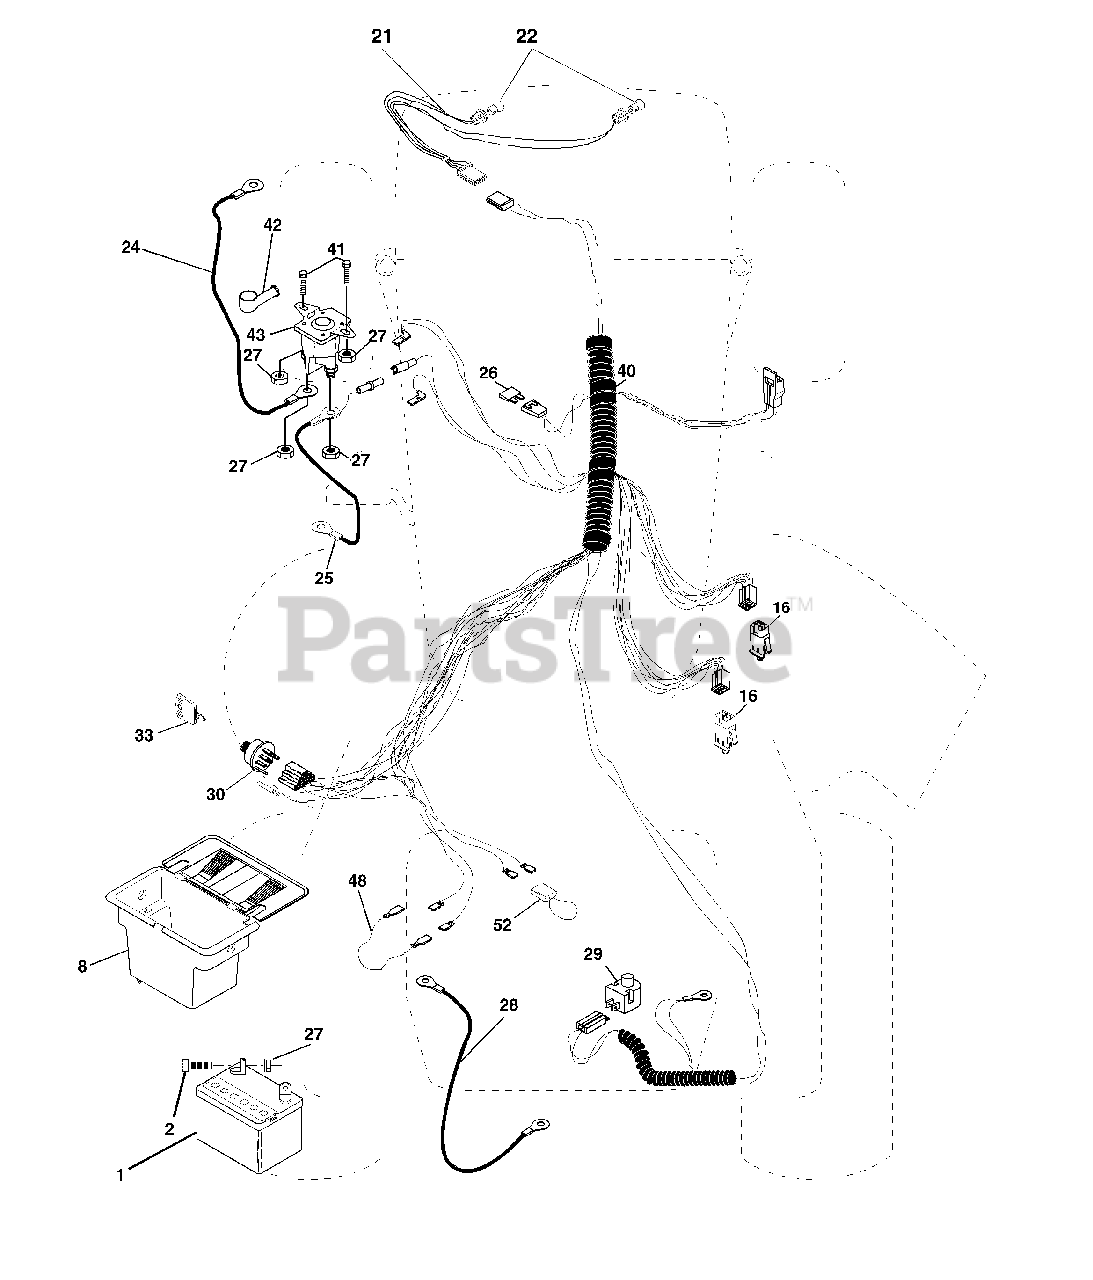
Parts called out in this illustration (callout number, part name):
1	Battery 12 Volt 25 Amp
2	Bolt Hex Hd 1/4-20unc X 3/4
8	Case Battery
16	Switch Interlock Push -In
21	Harness Asm Light W/4152J
22	Bulb Light #1156
24	Cable Battery 6 Ga 11" red
25	Cable Battery 6 Ga w/16 wire,red
26	Fuse 15 AMP
27	Nut Keps Hex 1/4-20 unc
28	Cable Ground 6 Ga 12" black
29	Switch Plunger Nc Gray
30	Switch Ign
33	Key Ign
40	Harness Ign
41	Bolt Blk Fin Hex 1/4-20 X 1/2
42	Cover Terminal Red
43	Solenoid
48	Adapter Ammeter Rectangular
52	Protection Wire Loop
